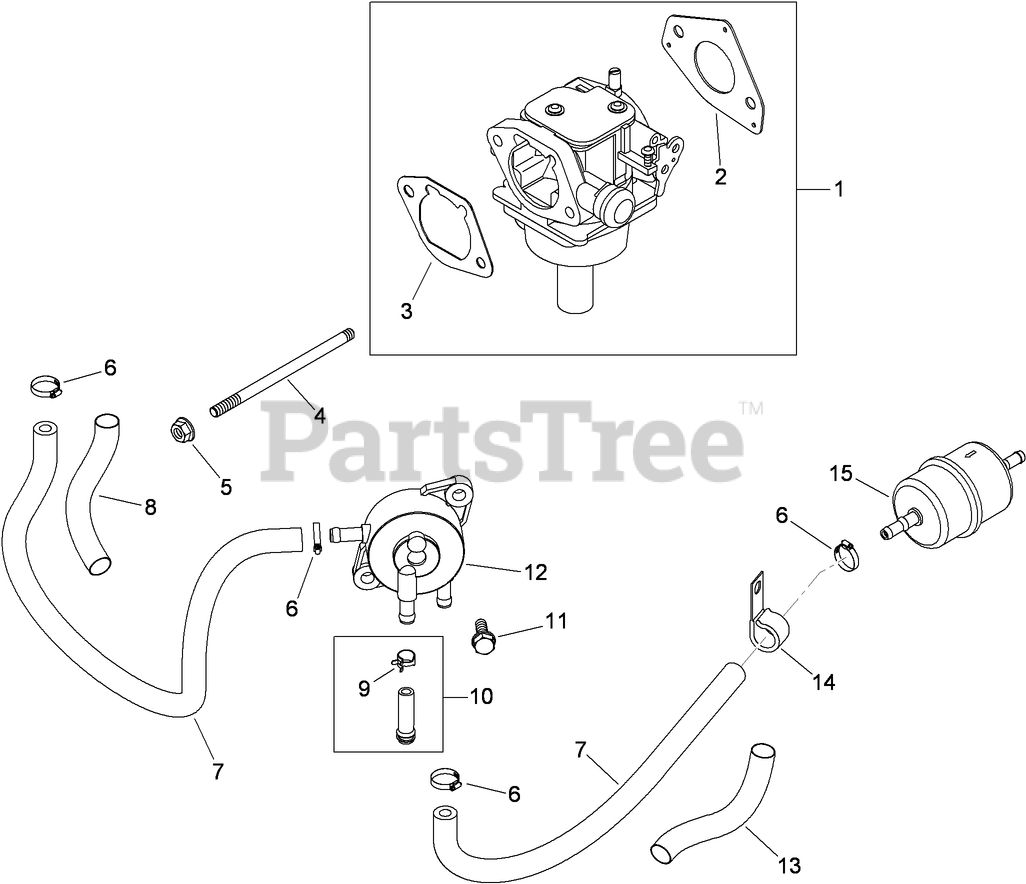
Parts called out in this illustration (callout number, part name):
1	CARBURETOR KIT-22mm KEIHIN (INCLUDES 2, 3)
2	GASKET-CARBURETOR
3	GASKET-BASE, AIR CLEANER
4	STUD (M6X1.0X106)
5	NUT-FLANGE (M6X1.0)
6	CLAMP-HOSE, SPRING (1/2)
7	LINE-FUEL (24-CUT TO LENGTH)
8	SLEEVE-ABRASION, ANTI
9	CLAMP-HOSE
10	FUEL PUMP HOSE W/CLAMP KIT (INCLUDES REF 36)
11	SCREW-TAP (M6X1.7X18)
12	PUMP-FUEL
13	SLEEVE-LINE, FUEL
14	CLIP-CABLE
15	Filter-Fuel
